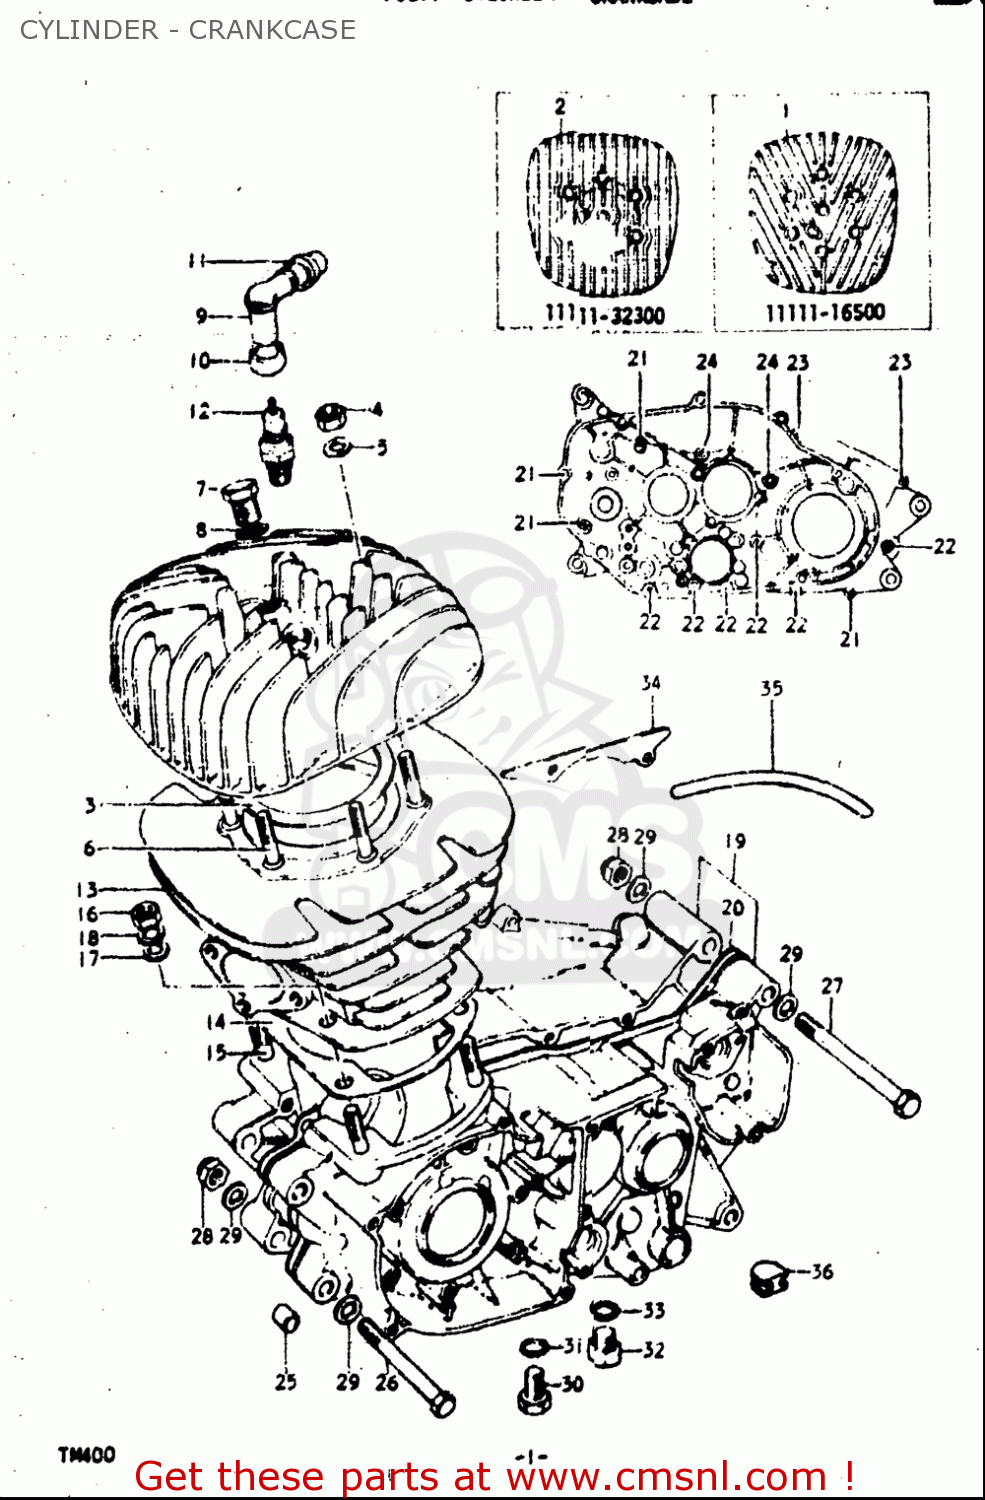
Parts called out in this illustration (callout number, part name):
3	GASKET,CYLINDER HEAD (NAS)
4	NUT
5	WASHER
6	BOLT,STUD
7	PLUG
8	GASKET(14X19.2X2) (NAS)
9	CAP ASSEMBLY,SPARK PLUG
10	SEAL,SPARK PLUG
12	PLUG,SPARK
14	GASKET,CYLINDER (MCA)
15	STUD BOLT
16	NUT
17	WASHER
18	WASHER,LOCK
20	GASKET,CRANKCASE (NAS)
21	SCREW
22	SCREW
23	SCREW
24	SCREW
25	PIN
26	BOLT
28	NUT
29	WASHER
30	PLUG
31	GASKET(10X14X3.6) (NAS)
32	PLUG
33	GASKET(14X19.2X2) (NAS)
36	PLUG
